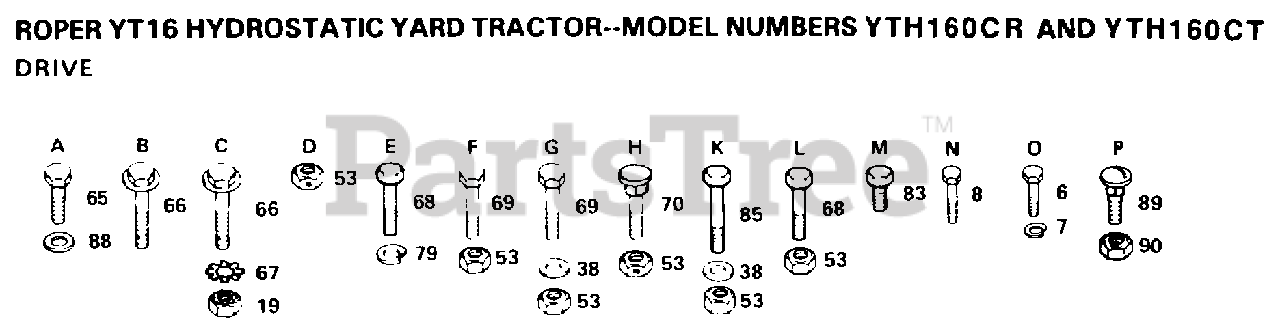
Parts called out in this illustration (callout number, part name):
6	BOLT
7	LOCKWASHER
19	NUT
38	WASHER
65	SCREW
66	SCREW LT
67	LOCKWASHER
69	BOLT
70	BOLT
79	LOCKWASHER
83	SCREW
85	BOLT
88	WASHER
89	BOLT
